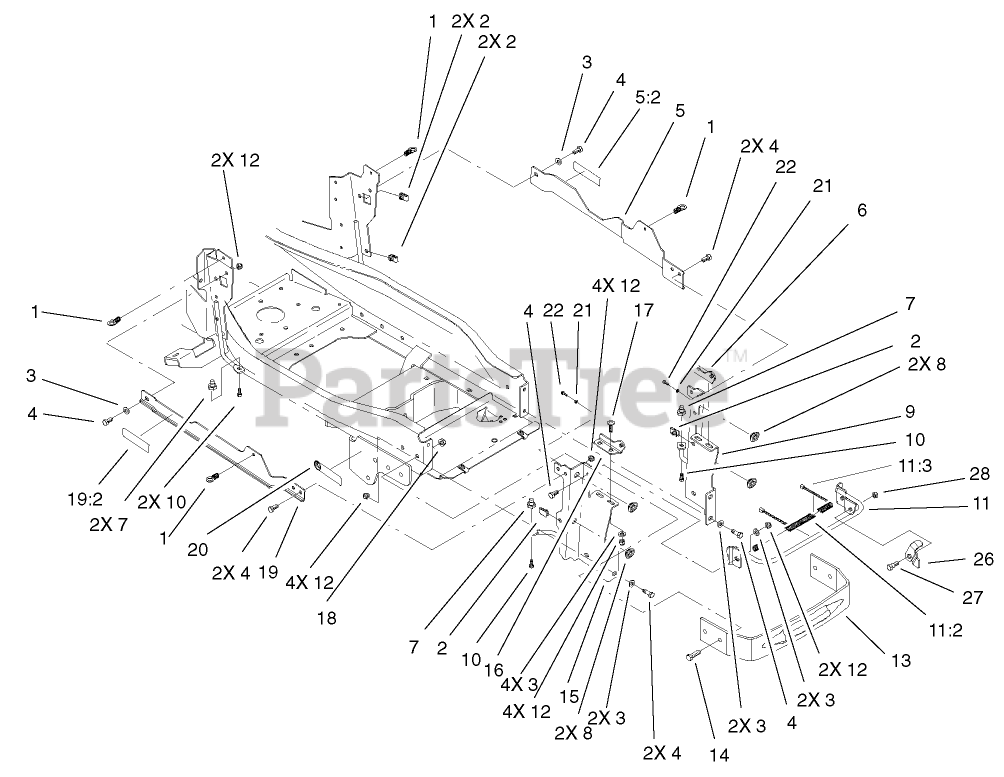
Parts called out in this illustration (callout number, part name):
1	LATCH ASM
3	WASHER-PLAIN
4	SCREW-HH
5	SUPPORT ASM
5	SUPPORT / DECAL ASM
5:2	DECAL-WARNING
5:2	DECAL - WARNING
6	BRACKET-HINGE, LOWER LH
7	MOUNT-SIDEPANEL
8	GROMMET
10	SCREW-PLASTITE
11:2	COVER-BRACE
11:3	TIE-CABLE
12	NUT-LOCK, NI
14	SCREW-HH
15	SUPPORT-HOOD, RH
16	BRACKET-HINGE, LOWER RH
17	SCREW-CARR
18	NUT-LOCK, NI
19	SUPPORT ASM
19:2	DECAL-WARNING
19:2	DECAL - WARNING
20	DECAL-ATTACH A-MATIC
21	WASHER-FLAT
22	SCREW-THD FORM, HWH
26	LEVER-PROP, HOOD
27	BOLT-SHOULDER,HFH
28	NUT-LOCK, NI
